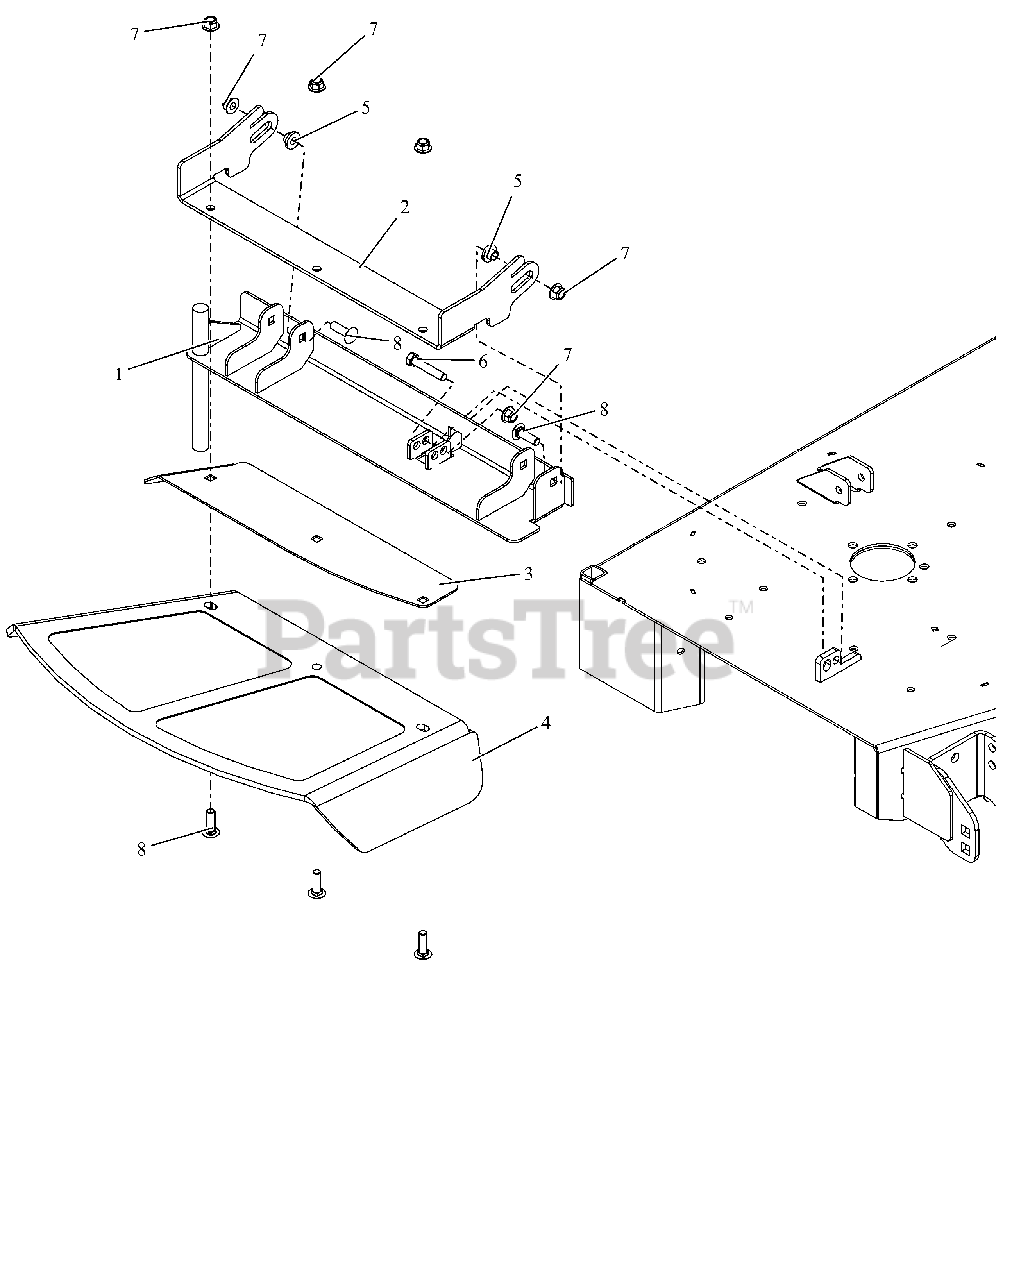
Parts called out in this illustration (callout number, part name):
1	48-60 DISCH CHT MTG WMT W/SAFE
2	48-60" CHUTE MTG BRKT - RED
3	48-60 DISCH CHUTE CLMP PLT-RED
4	CHUTE,48-60" FRMD RUBBER DISCH
5	BSHG-FLG .385X.500X.875X.406
6	BLT,HEX .38-16X2.00 G5 ZCC
7	NUT,NYL-FLG .38-16 GF ZCC
8	BLT,RHSSN .38-16X1.25 G5 ZCC
